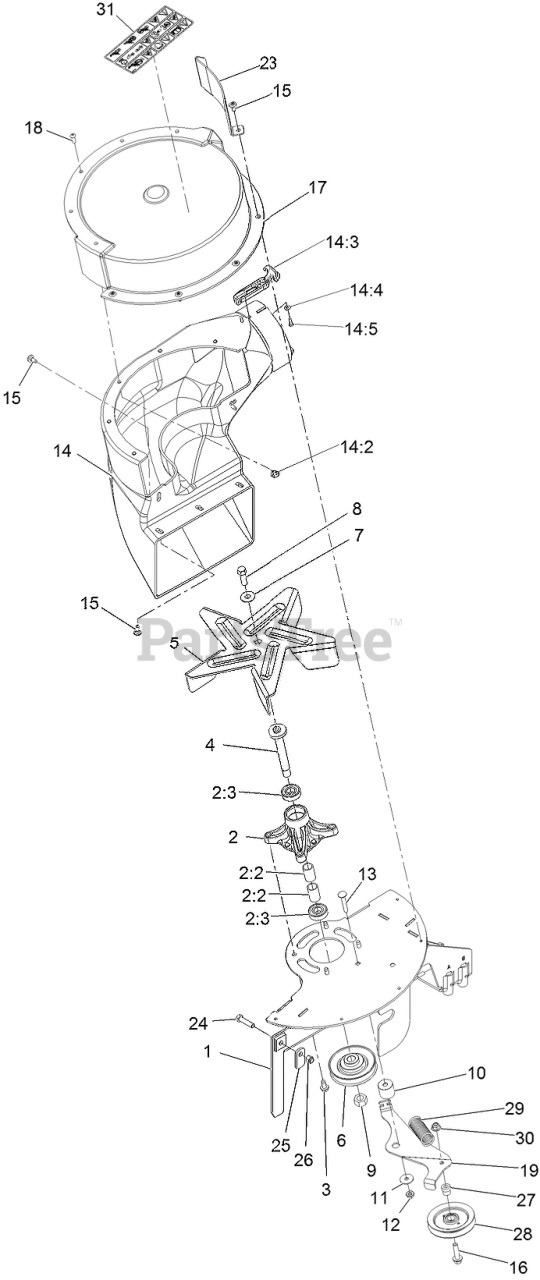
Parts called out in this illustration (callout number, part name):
1	WELDMENT-SUPPORT, BLOWER
2	SPINDLE ASM
2:3	BEARING-BALL
3	Screw-HWH 5/16-18 X 3/4 Tf
4	Shaft - Spindle
5	Fan-Blower
6	SHEAVE-BLOWER OFFSET
7	WASHER-BELLEVILLE
8	Screw-HH
9	Nut-Hex
10	SPACER-STEPPED
11	WASHER-PIVOT
12	NUT-HF, NI
13	SCREW-CARR
14	ASM-Blower Chute, Plastic
14:2	Insert-T-Nut
14:3	LATCH-RUBBER
14:4	WASHER-FLAT
14:5	SCREW-PPH
15	SCREW-SHOULDER
16	SCREW-HHF
17	ASM-BLOWER COVER
18	SCREW-PRH
19	ARM-IDLER, BLOWER
23	Guard-Blower
24	SCREW-HH
25	LATCH-CATCHER, GRASS
26	NUT-LOCK, NI
27	HUB,SPACER
29	SPRING-IDLER
30	NUT-HF, NI
31	DECAL-WARNING BLOWER W/RO
